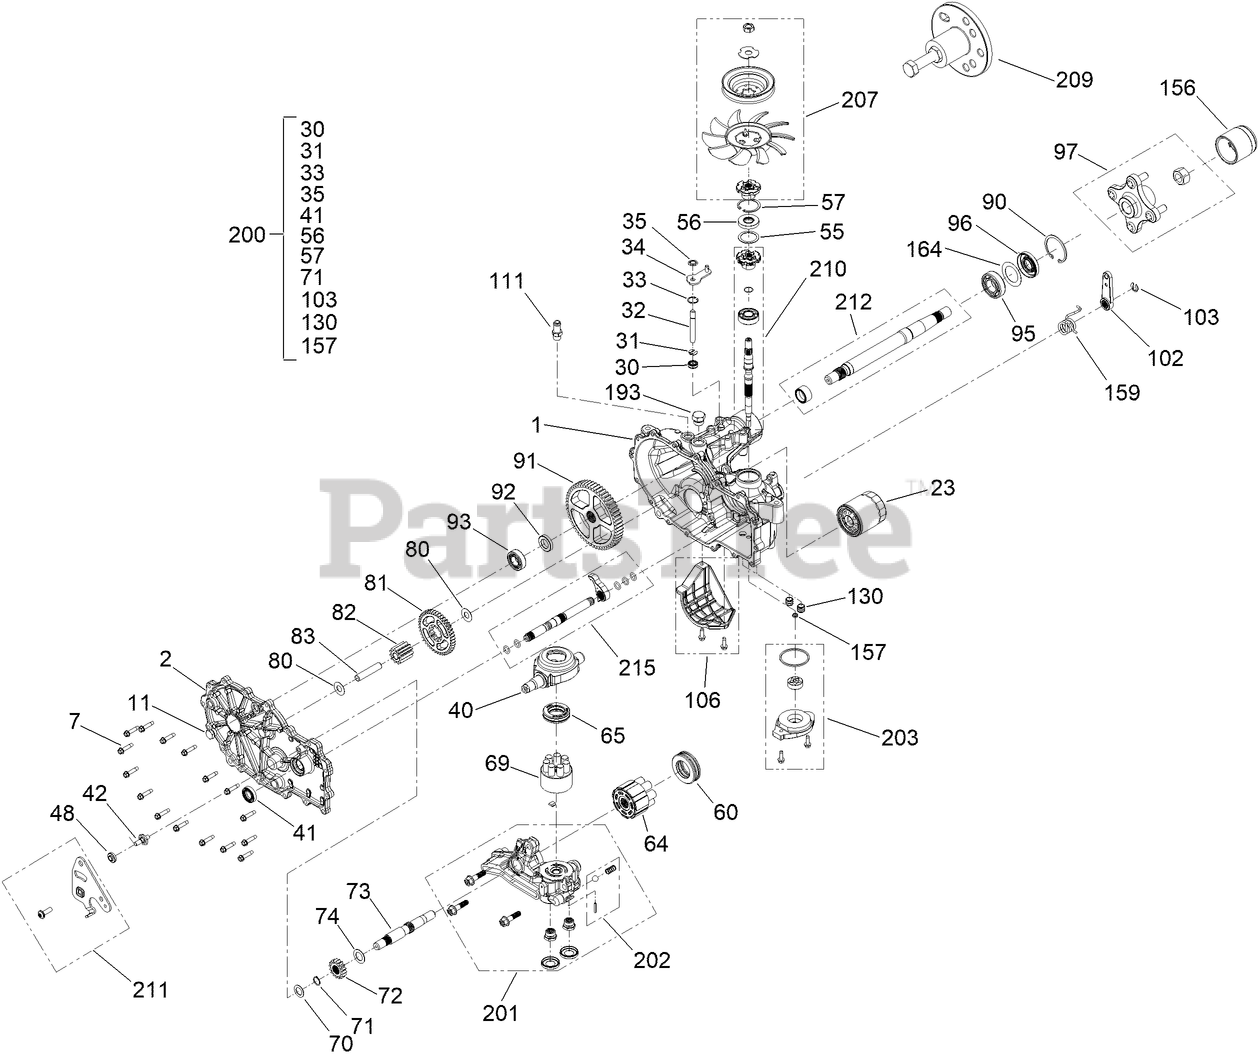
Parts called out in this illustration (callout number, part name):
1	KIT, MAIN HOUSING LH, CHARGE
2	KIT, SIDE COVER LH, CONTROL
7	SCREW-HHF
23	ELEMENT-OIL FILTER, HYD
30	SEAL-LIP
31	RING-RETAINING, EXTERNAL
32	ROD-BYPASS
33	RING-RETAINING, INTERNAL
35	RING-RETAINING, EXTERNAL
40	SWASHPLATE-TRUNNION
41	SEAL-LIP
48	SPACER
55	SPACER
56	SEAL-LIP
57	RING-RETAINING
60	BEARING-THRUST
64	CYLINDER BLOCK ASM KIT
65	BEARING-THRUST
69	PUMP BLOCK ASM
70	WASHER-FLAT
71	RING-RETAINING
72	GEAR-16T
73	SHAFT-MOTOR
74	WASHER
80	WASHER
81	GEAR-43T
82	GEAR-11T
83	PIN-JACKSHAFT
90	RING-RETAINING
91	GEAR-54T
92	SPACER
93	BEARING-BALL
95	BEARING-BALL
97	HUB KIT
102	HANDLE-BRAKE
103	RING-RETAINING, EXT
106	FILTER GUARD KIT
111	ADAPTER-STRAIGHT
130	TUBE-CHARGE
156	COVER-NUT, AXLE
157	GEROTOR SEAL KIT
159	SPRING, TORSION, CW
164	SPACER
200	SEAL KIT
201	LH CENTER SECTION KIT
202	CHARGE RELIEF KIT
203	CHARGE KIT
207	FAN AND PULLEY KIT
209	HUB PULLER KIT
210	INPUT SHAFT KIT
211	KIT, ARM, CONTROL
212	AXLE SHAFT KIT
215	KIT, OUTBOARD, RH ROT B / LH ROT A
